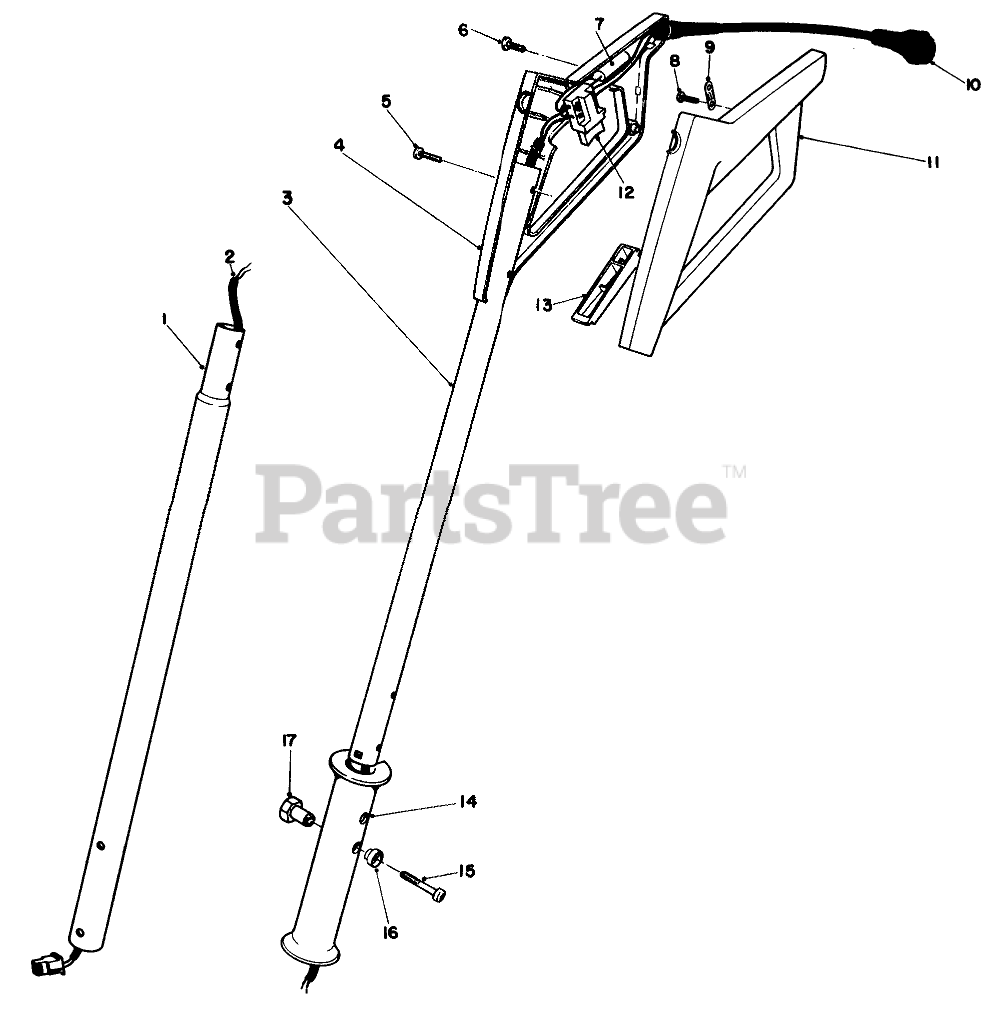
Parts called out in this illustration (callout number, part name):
1	LOWER TUBE, P. SHOVEL
2	Wire Harness
3	Tube-Upper Handle
4	RH GRIP
5	Screw
6	SCREW-PPH
7	CAPACITOR
8	Screw, Pan Head
9	Clamp-Power Cord
10	Power Cord-Upper Wiring Harness
11	LH GRIP
12	Switch
13	Switch Bar
14	Grip-Handle
15	SPEC PAN HD SCREW
16	Bushing-Screw
17	SPECIAL HEX NUT
